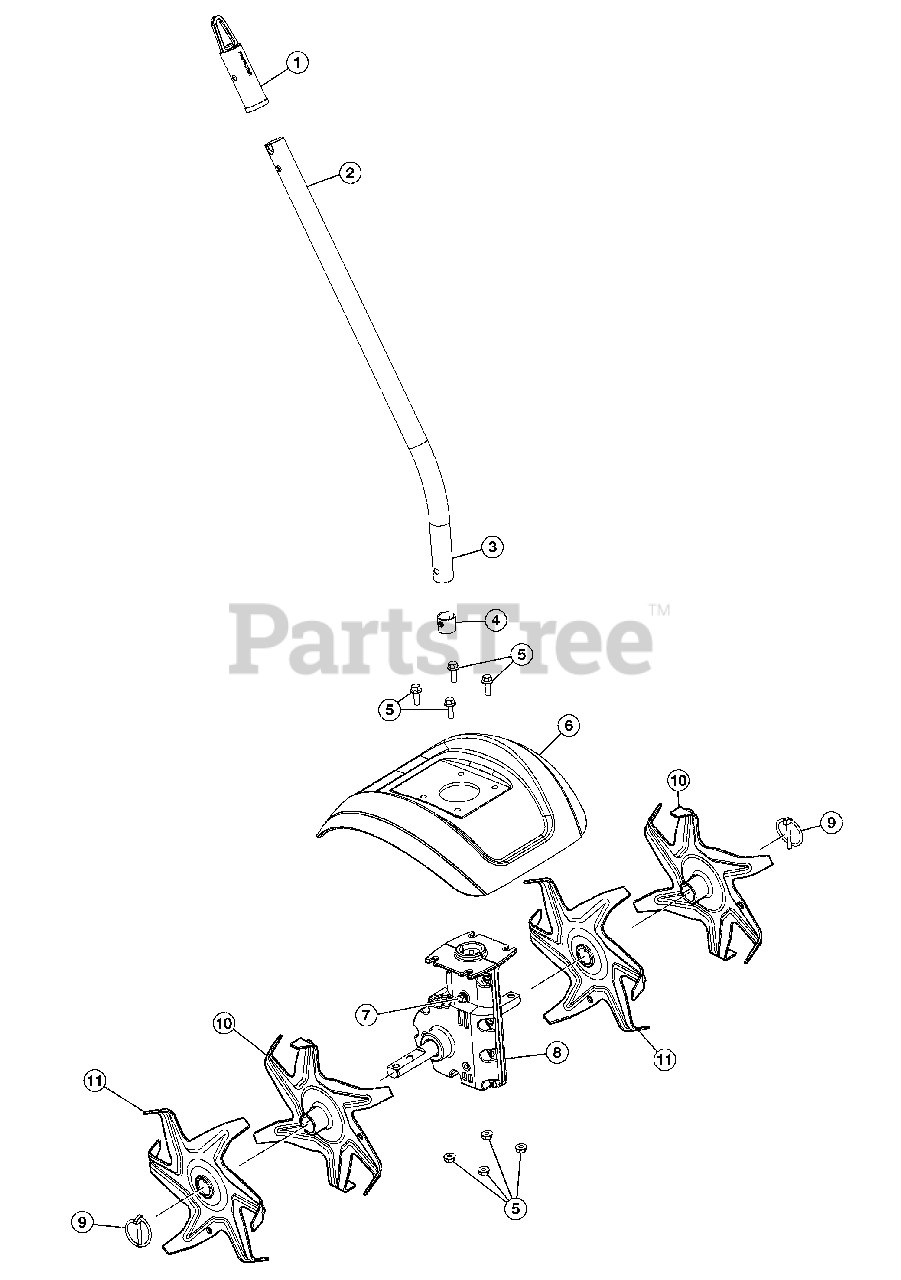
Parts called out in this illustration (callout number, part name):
1	Accessory Hanger
2	Drive Shaft Housing Assembly
3	Flexible Drive Shaft
4	Retainer Sleeve
5	Mounting Hardware Set
6	Tine Shield
8	Gear Box Assembly
9	Clip Pin
10	Tine (Left Inner, Right Outer)
11	Tine (Left Outer, Right Inner)
